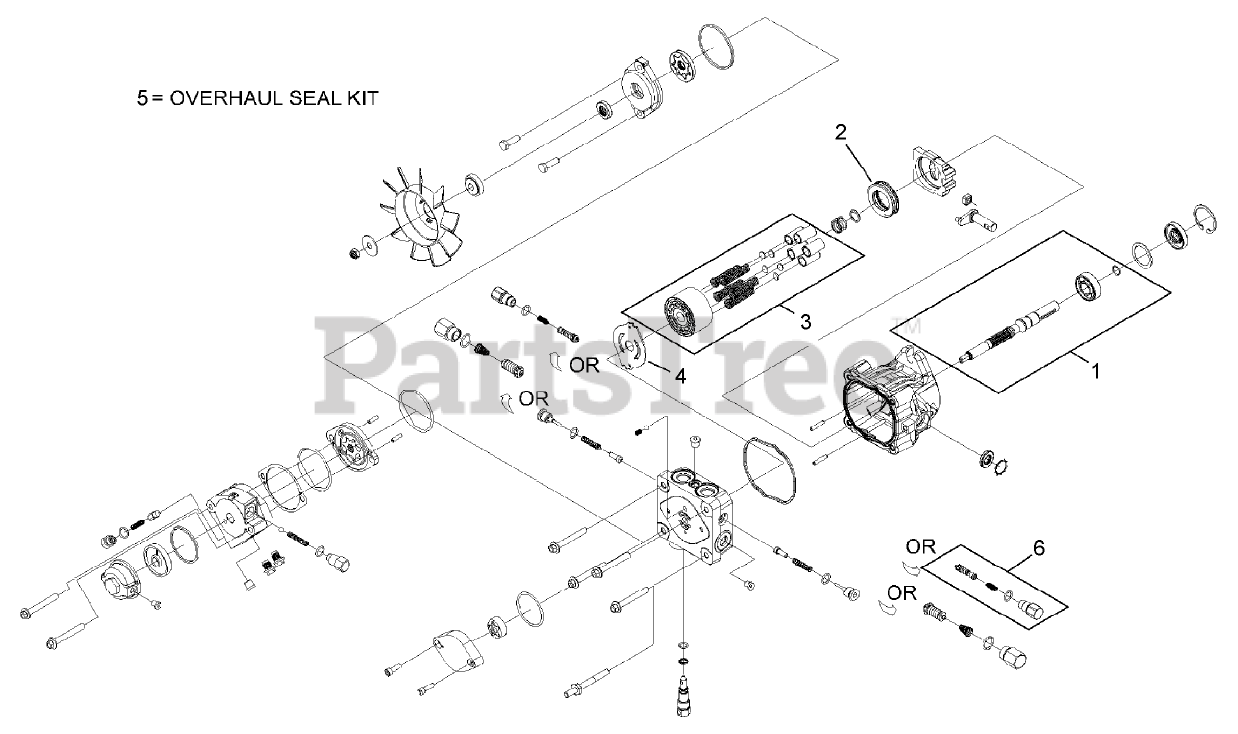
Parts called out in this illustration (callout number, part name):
1	INPUT SHAFT KIT
2	THRUST BEARING KIT
3	CYLINDER BLOCK KIT
4	Plate-Valve
5	SEAL OVERHAUL KIT
6	SHOCK VALVE KIT
